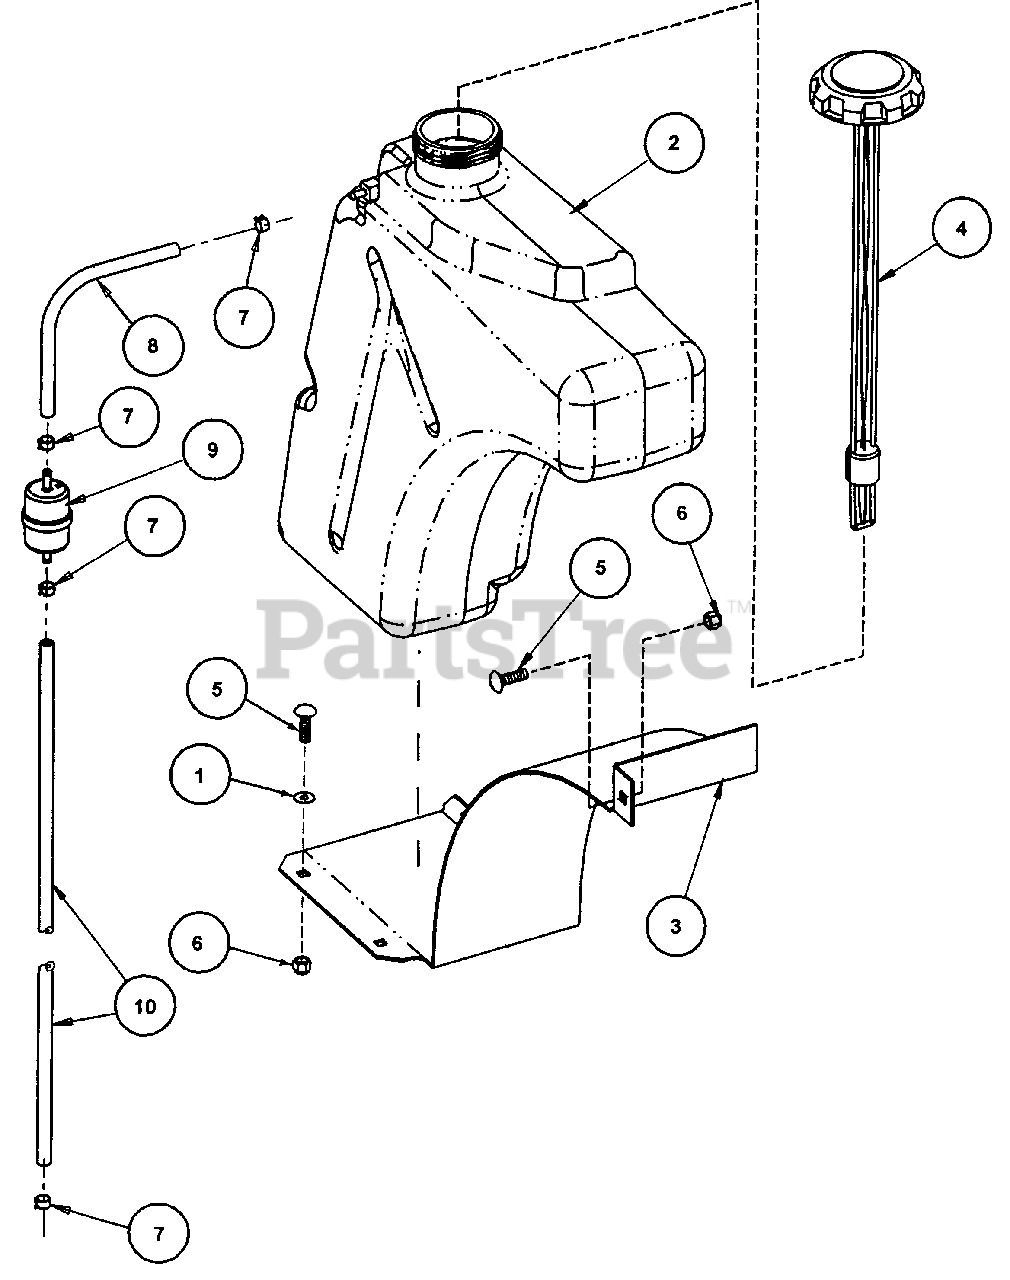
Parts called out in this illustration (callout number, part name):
1	RETAINER, 3/8 Bolt
2	TANK, Fuel
3	BRACKET, Fuel Tank Support
4	ASSEMBLY, Cap/Gauge
5	BOLT, 3/8-16 x 1" Carriage, Grade 5
6	NUT, 3/8-16 HEX NYLON LOCK
7	CLAMP, Fuel Hose
8	HOSE, Fuel 1/4 x 4"
9	FILTER, Fuel
10	HOSE, Fuel 1/4 x 24"
